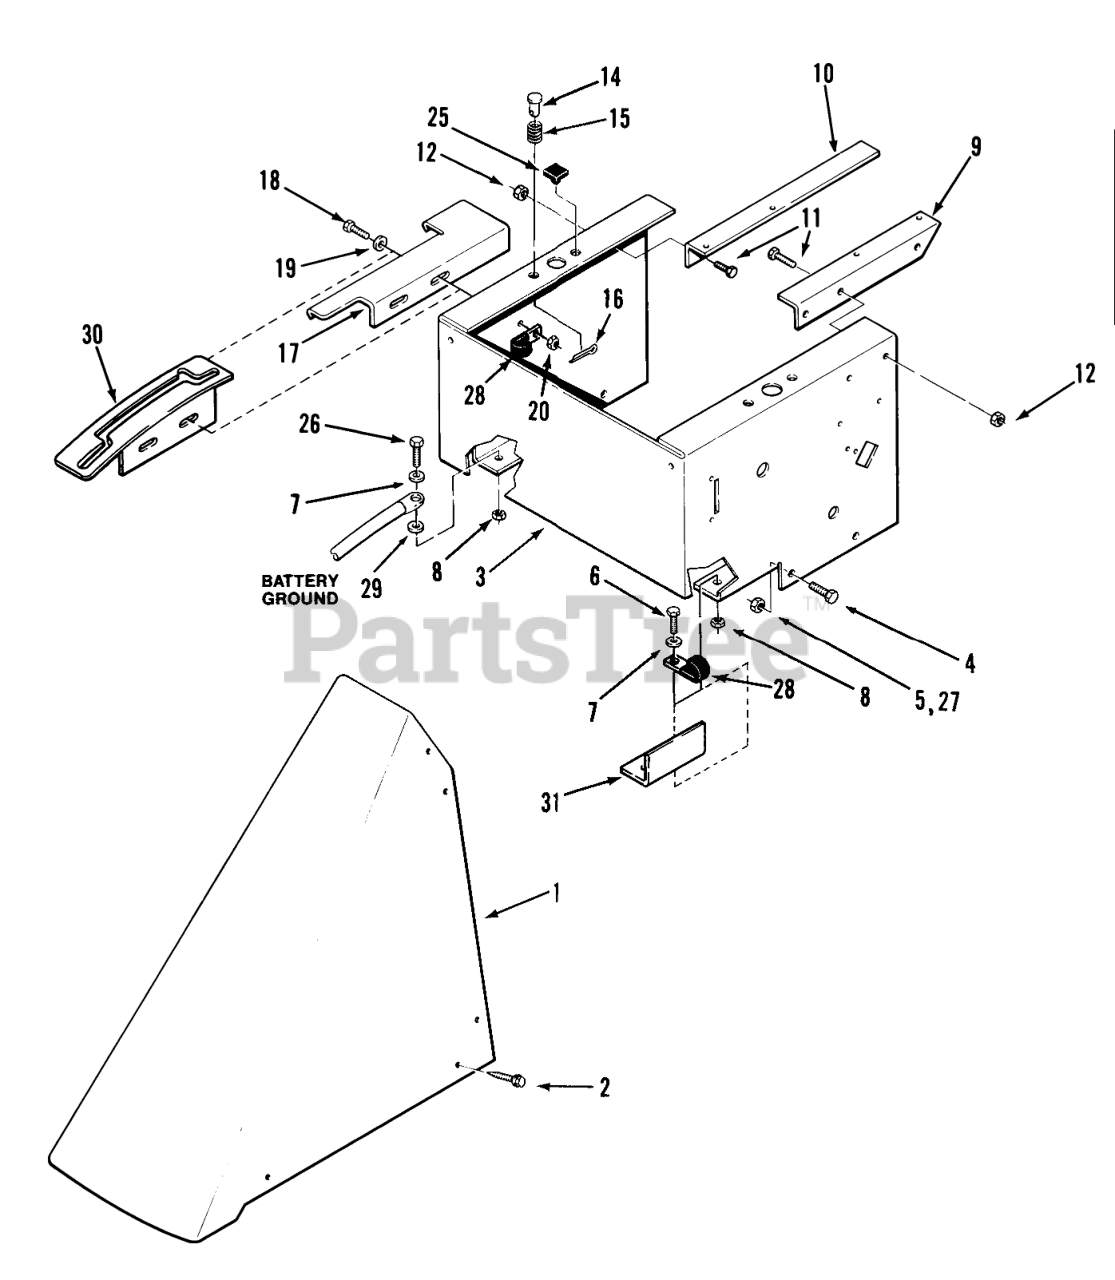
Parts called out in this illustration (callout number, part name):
1	COVER CONSOLE R
2	HEX WASHER STS
3	SUPPORT-SEAT R
4	BOLR HWH 3/8-16X7/8
5	NUT
6	Bolt
7	WASHER 5/16 SAE
8	Nut
9	ANGLE TANK SUPP. R
10	ANGLE TANK SUPP. R
11	H H C S
12	Nut
15	SPRING
16	Cotter Pin
17	PLATE SHIFT R
18	Bolt
19	WASHER 5/16 SAE
20	Nut
25	BUMPER SJ5514 BLACK
26	Bolt
27	Nut
28	CLIP
29	Washer-Lock
30	Shift Quadrant 112-C Only
31	Bracket 112-C Only
